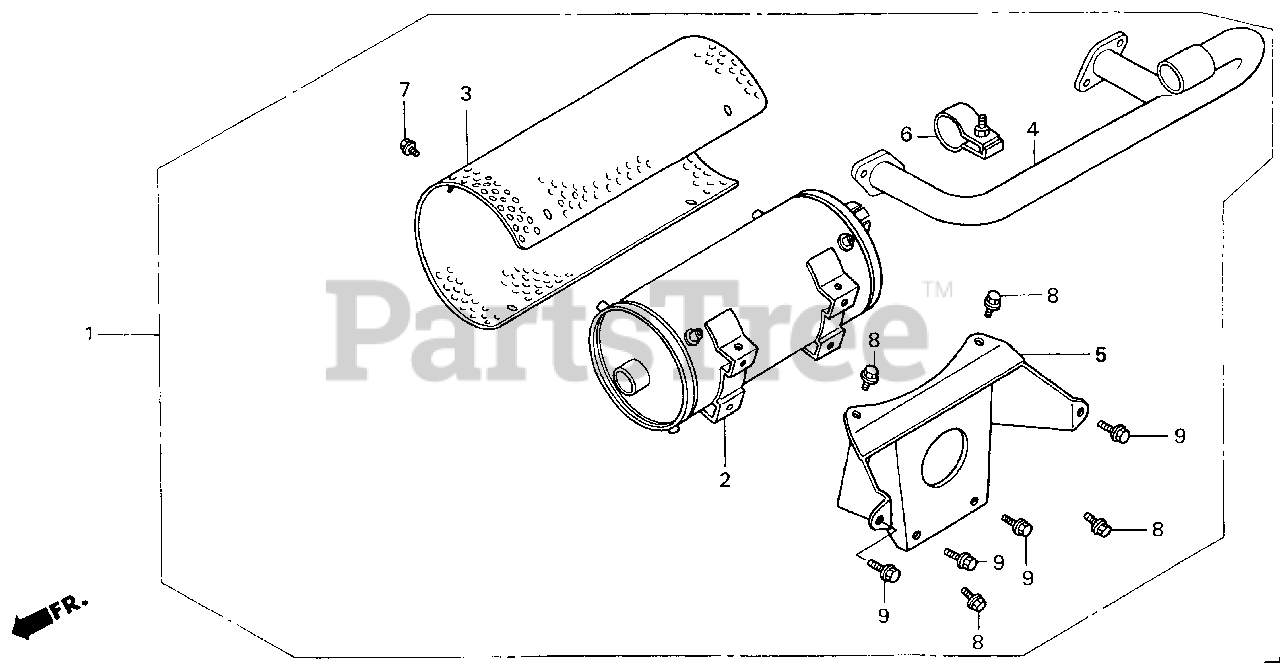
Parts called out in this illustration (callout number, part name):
1	MUFFLER KIT (HIGH-B) (N/A: SEE COMPONENTS)
2	MUFFLER (HIGH)
3	PROTECTOR, MUFFLER (HIGH)
4	PIPE, EX. (HIGH-L)
5	STAY, MUFFLER (HIGH)
6	BAND ASSY.
7	BOLT, FLANGE (6X8)
8	BOLT, FLANGE (8X14)
9	BOLT, FLANGE (8X20)
